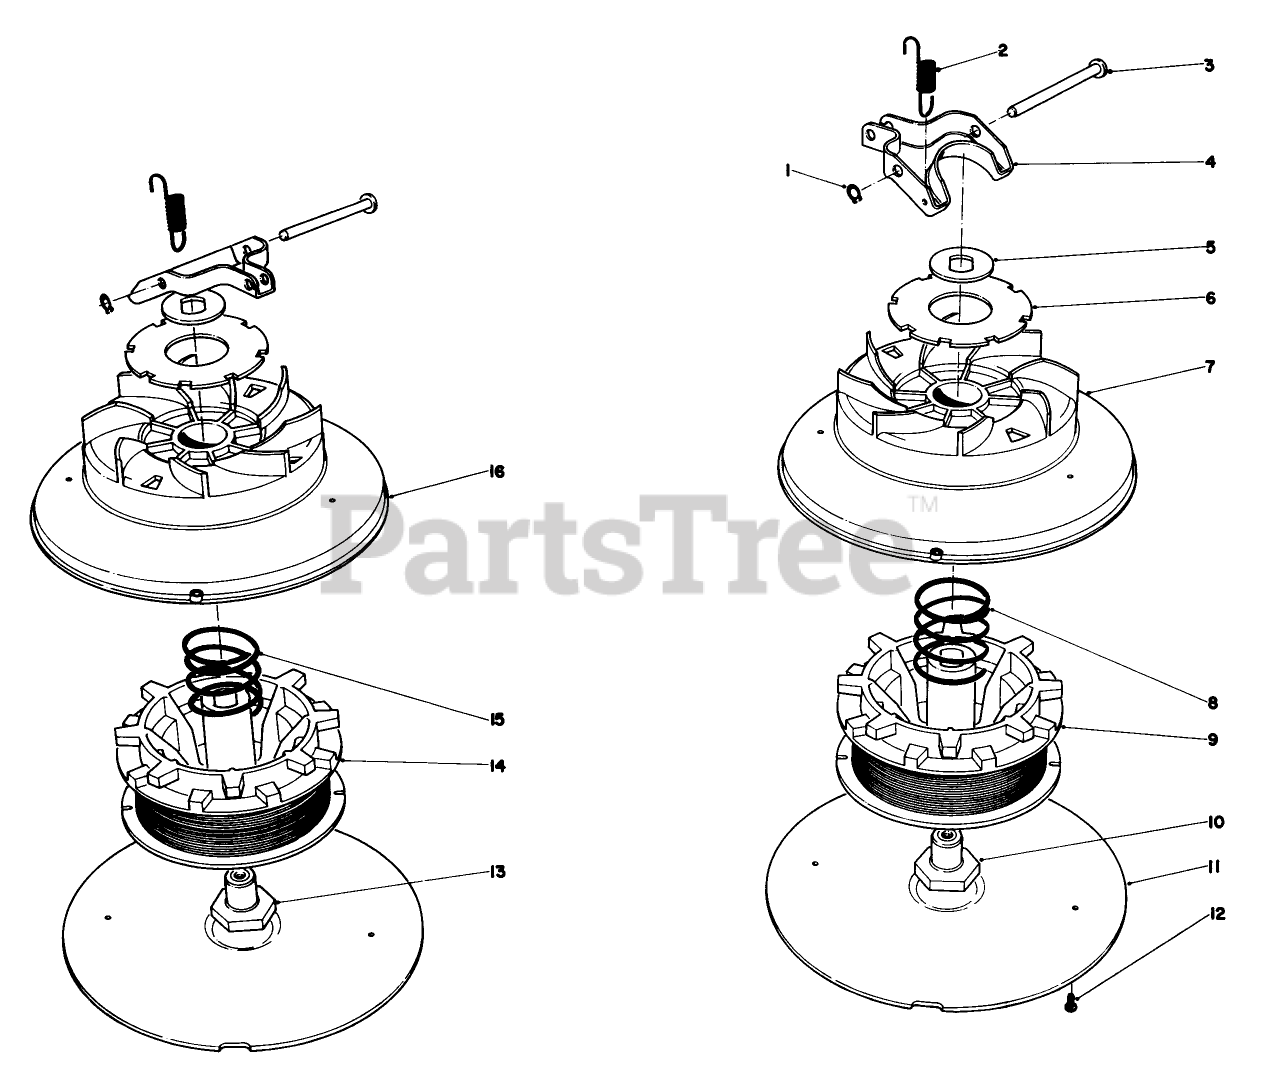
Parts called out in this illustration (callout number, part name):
7	LH DRUM ASM
9	Spool Assy. L.H.
14	Spool Assy. R.H.
